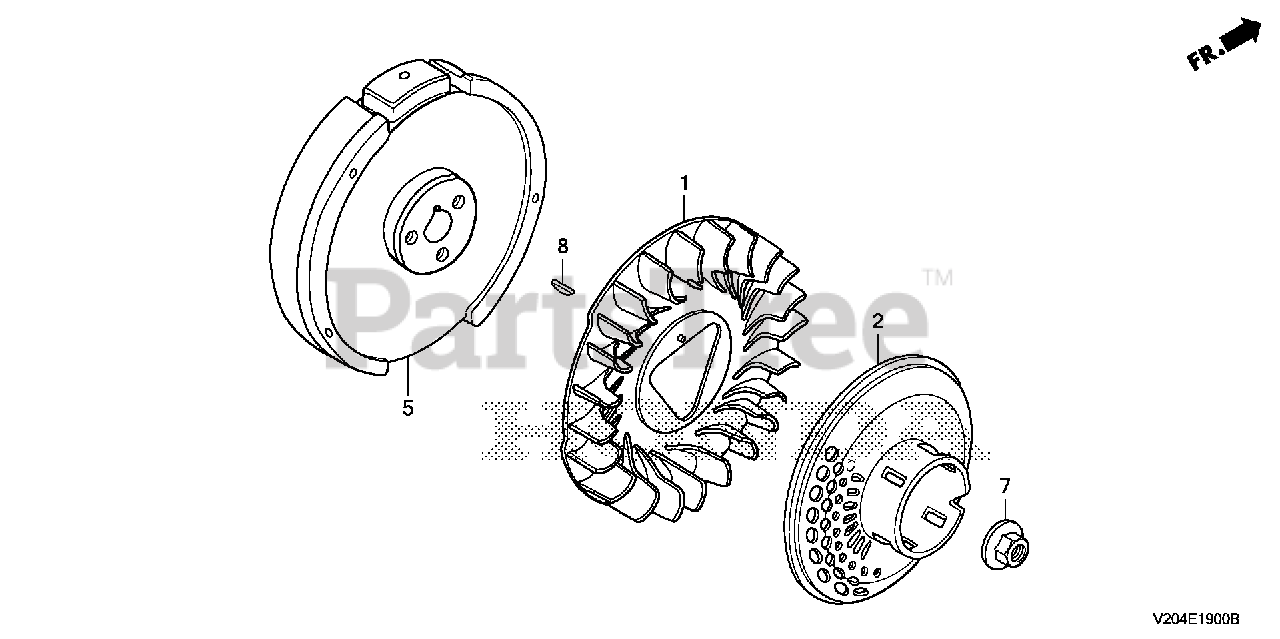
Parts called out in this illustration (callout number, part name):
1	FAN, COOLING
2	PULLEY, STARTER (SCREEN GRID)
7	NUT, SPECIAL (16MM) (1)
8	KEY, SPECIAL WOODRUFF (25X18)
